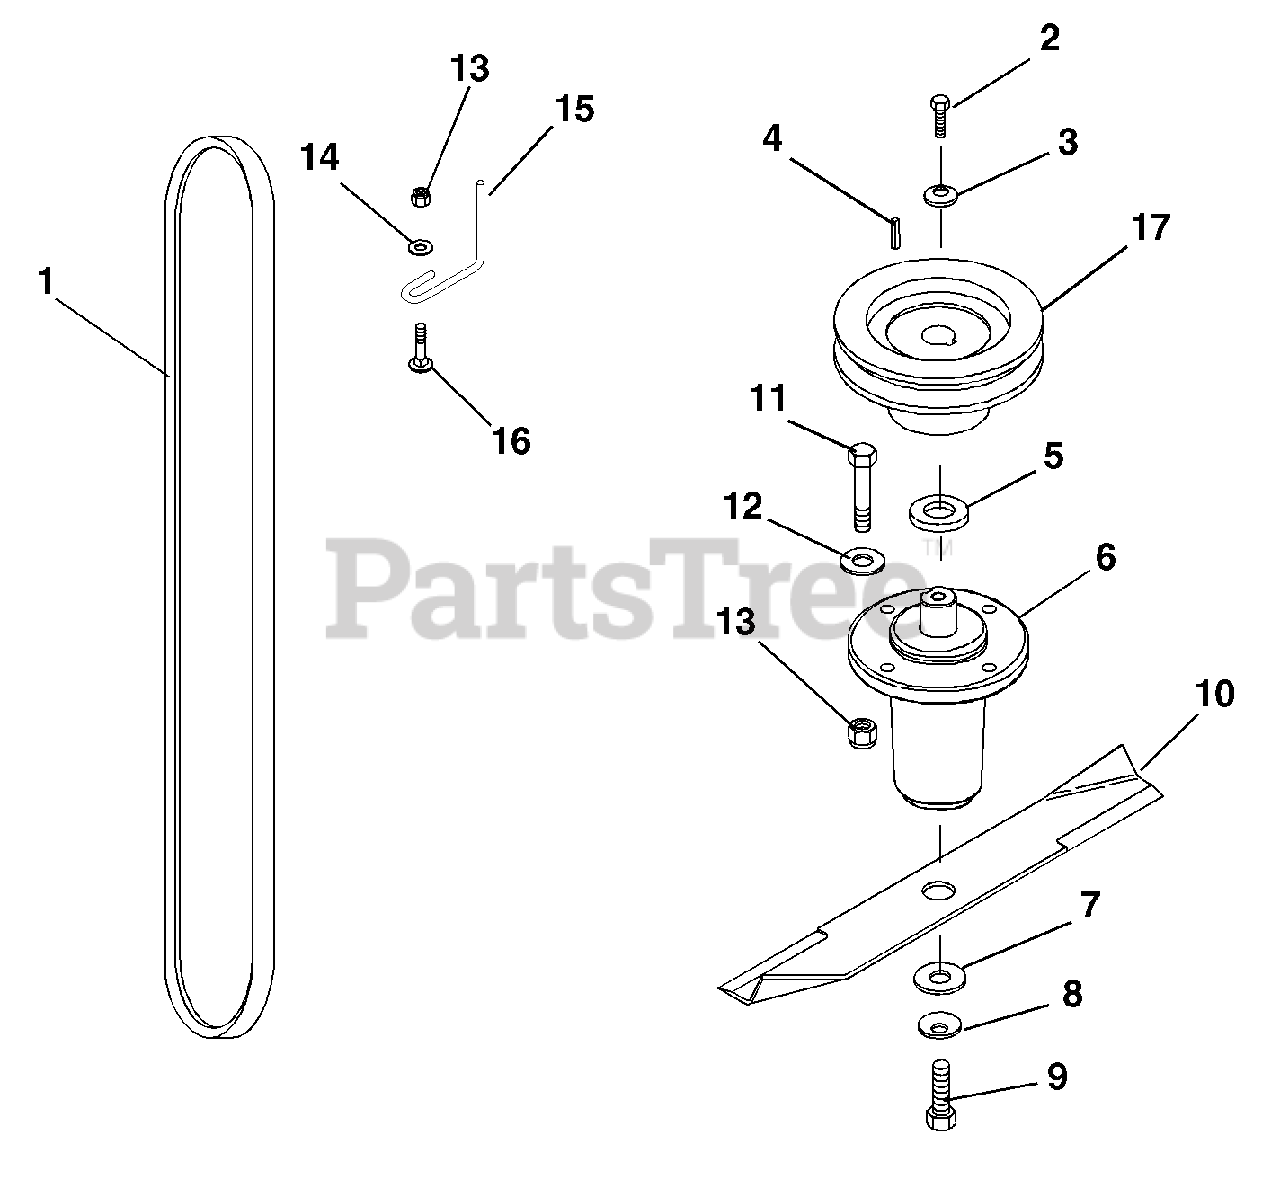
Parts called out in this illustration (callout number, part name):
1	V-Belt A-Section
2	Bolt-Hex .38-16 x 1.00 Grade 8
3	Washer-Cupped-Serrated .375
4	Key-Straight .25 x 1.00 x .25
5	Slinger-Dust
6	Assembly-Spindle
7	Washer-Flat .640 x 1.81 x .250
8	Washer-Bellville .63 x 1.625 x .14
9	Bolt-Blade
10	Blade - 36" Mower
11	Bolt-Hex .38-16 x 1.50 Grade 5
12	Washer-Flat-Steel .438 x 1.00 x .083
13	Nut-Locking-Nylon .38-16
14	Washer-Flat-Steel .406 x .812 x .065
15	Belt Brake Finger 2-Deck Clutch
16	Bolt-Round Head Square Neck .38-16 x 1.25 Grade 5
